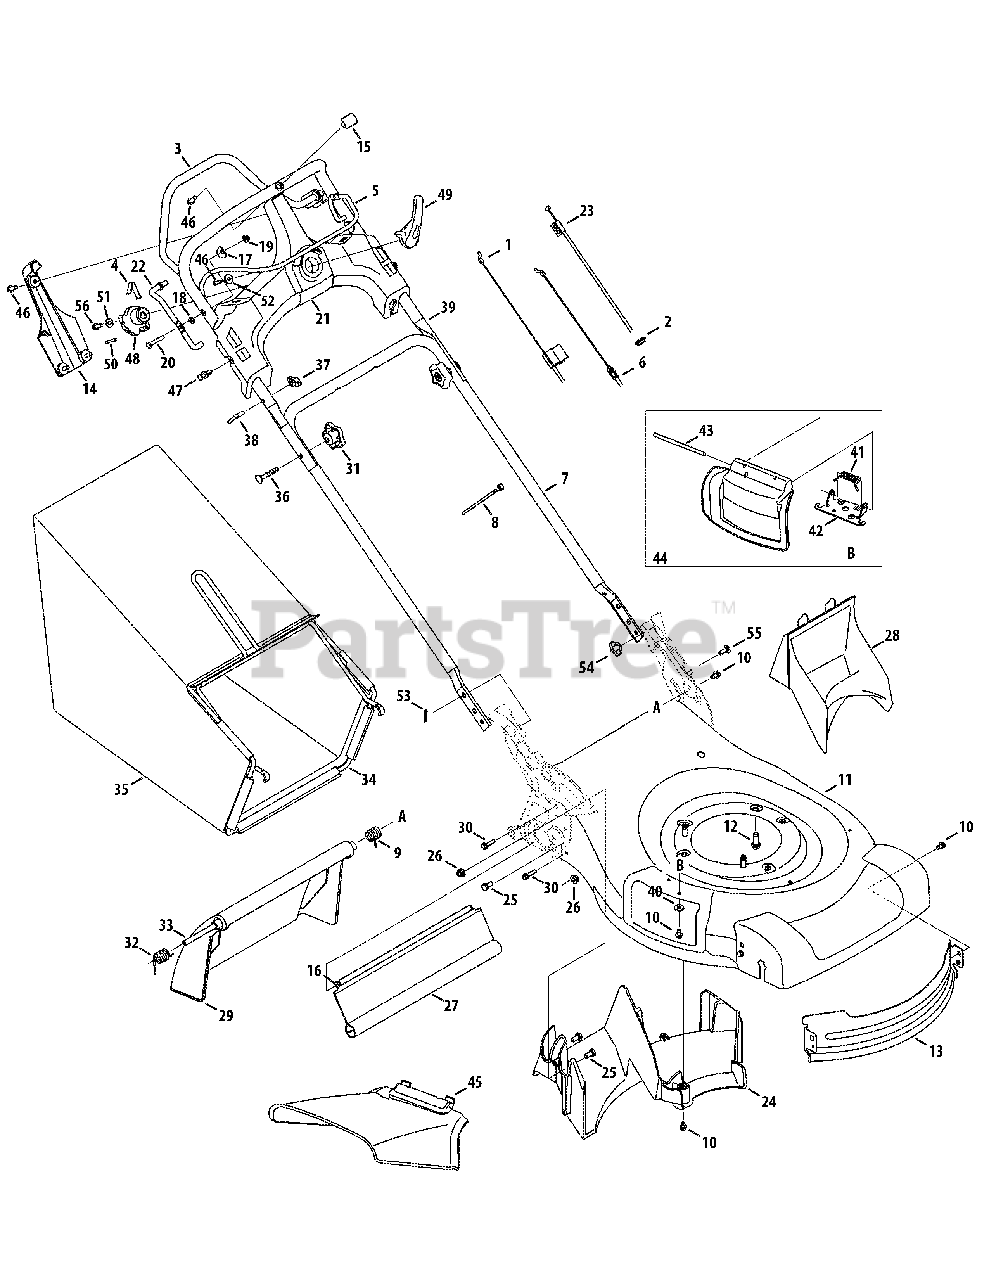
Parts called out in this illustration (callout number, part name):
1	Drive Cable
2	Rubber Grommet
3	Drive Control
4	Shift Spring
5	Blade Control
6	Control Cable
8	Cable Tie
9	Torsion Spring, LH
10	TT Screw, 1/4-20 x .500
13	Front Deck Baffle
14	Variable Speed Cont. Panel Cover
15	Variable Speed Cont. Panel Cover
16	Screw, #10-16 x .500
17	Saddle Washer
18	Washer, Lock, 1/4
19	Nut, Flange Lock, 1/4-20
20	Screw, 1/4-20 x 1.50
21	Variable Speed Control Panel
22	Bail Pivot Rod - RH
22	Bail Pivot Rod - LH
23	Variable Speed Cable
24	Rear Baffle
25	Screw, 5/16-18 x .625
26	Flange Lock Nut, 5/16-18
27	Trailshield
28	Mulch Plug
29	Rear Door
30	Screw, 1/4-15 x 1.00
31	Star Knob
32	Torsion Spring, RH
33	Door Pivot Rod
36	Carriage Bolt, 5/16-18 x 2.00
40	Bell Washer, .265 x .75 x .062
41	Torsion Spring
42	Chute Deflector Adapter
43	Hinge Pin
44	Mulch Plug Assembly
45	Side Discharge Chute
46	Screw, #12-16 x .75
47	Rivet, Plastic
48	4 Speed Actuator
49	Speed Selector Level
51	Washer, Flat, .25 x .630 x .0515
52	Washer, Flat, .250 x .750 x .119
53	Cotter Pin
54	Wing Nut
55	Carriage Bolt, 1/4-20
56	Screw, 1/4-15 x .750
